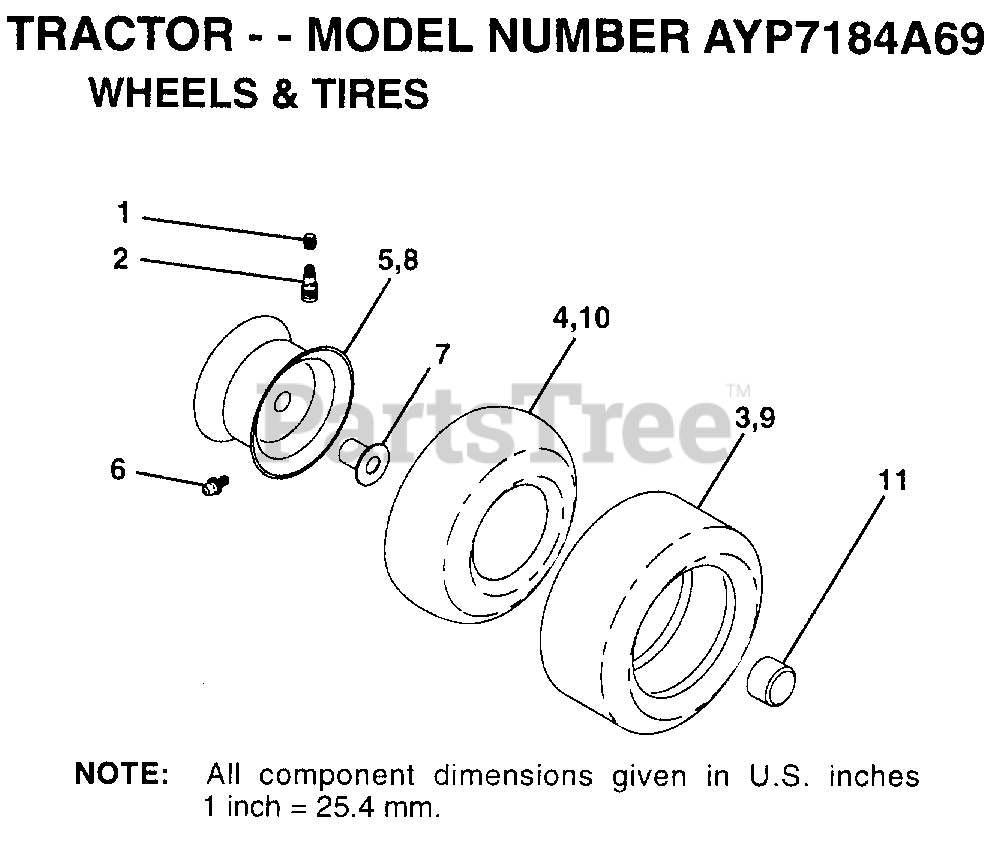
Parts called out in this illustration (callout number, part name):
1	VALVE CAP
2	VALVE STEM LT
4	TUBE.5.3/4.5/6
5	"RIM ASM 6"" FRT"
6	FITTING LT
7	"FLANGE, BEARING"
8	"RIM AS 8"" REAR"
9	TIRE.20X8-8
10	TUBE.18X9.5-8
11	HUB CAP
